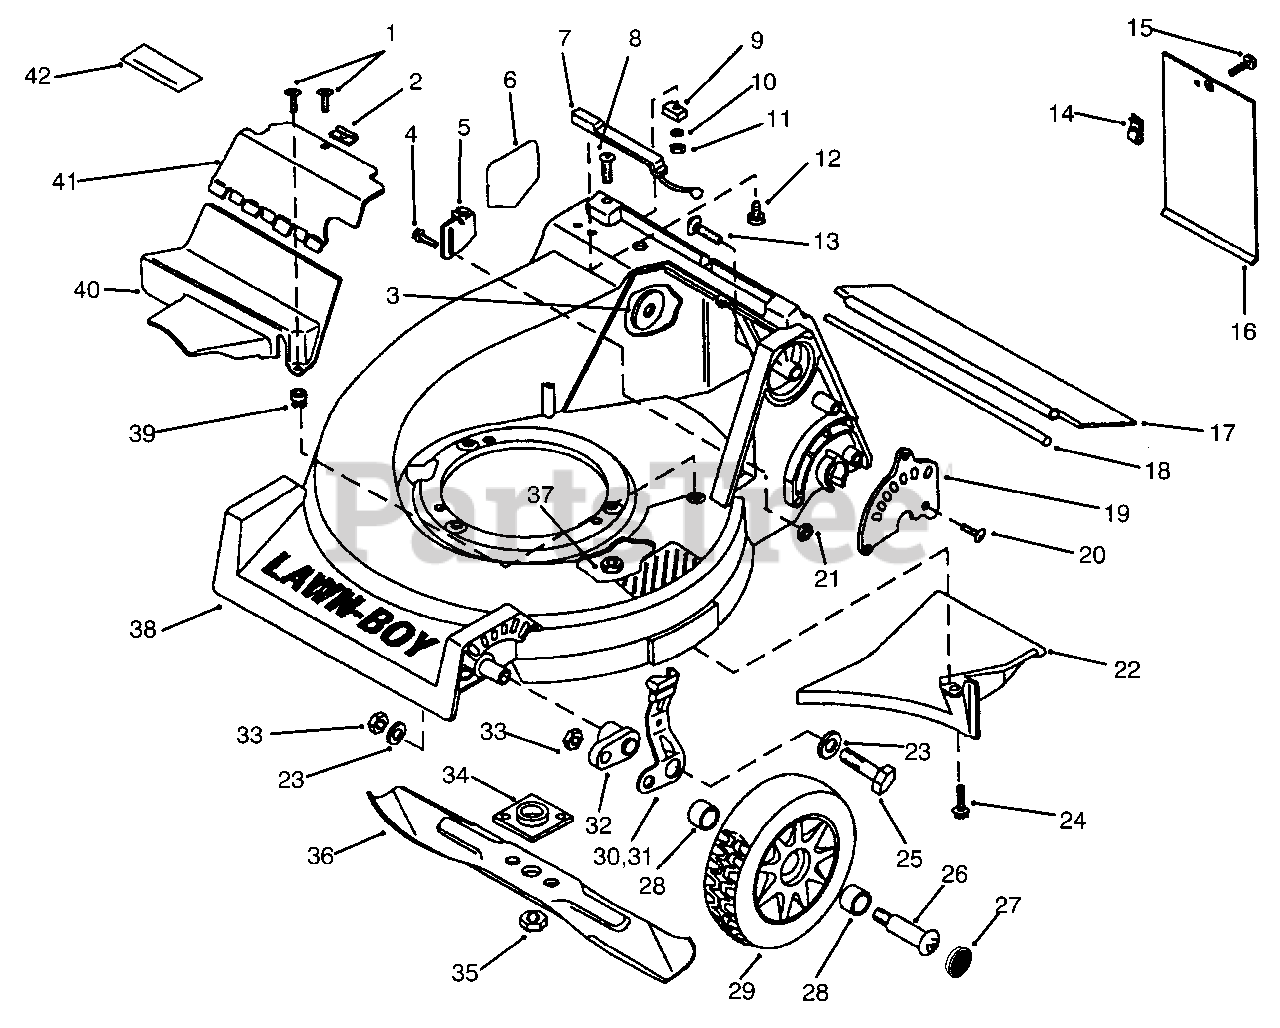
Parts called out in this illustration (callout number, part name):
2	Speednut
3	Washer-R.H. Handle
5	Anchor-Cable
6	Decal-Blade Warning
7	Switch-Bag Lock
9	Assembly-Magnet
10	Lockwasher
13	Bolt-Handle Mounting
14	Speednut
16	Door-Access
17	Shield-Trailing
18	Rod-Trailing Shield
19	Plate-Height Adjust
20	Screw-Plate to Housing
21	Nut-Cable Anchor/Hsg.
24	Screw-Baffle to Housing
26	Shoulder Bolt-Wheel
29	Assembly-Wheel & Tire (Incl. Ref. No. 28)
30	Assy.-Knob & Spring, L.H.
32	Arm-Front Height Adj.
34	Assembly-Collar & Plate
35	Nut-Blade
36	Blade-21"
37	Locknut-Mtg Plate/Hsg.
38	Assembly-Housing (Incl. Ref. No. 3,6,13,22, & 24)
39	Grommet
40	Cover-Lower Drive
41	Cover-Upper Drive (Incl. Ref. No. 42)
42	Decal-Warning
